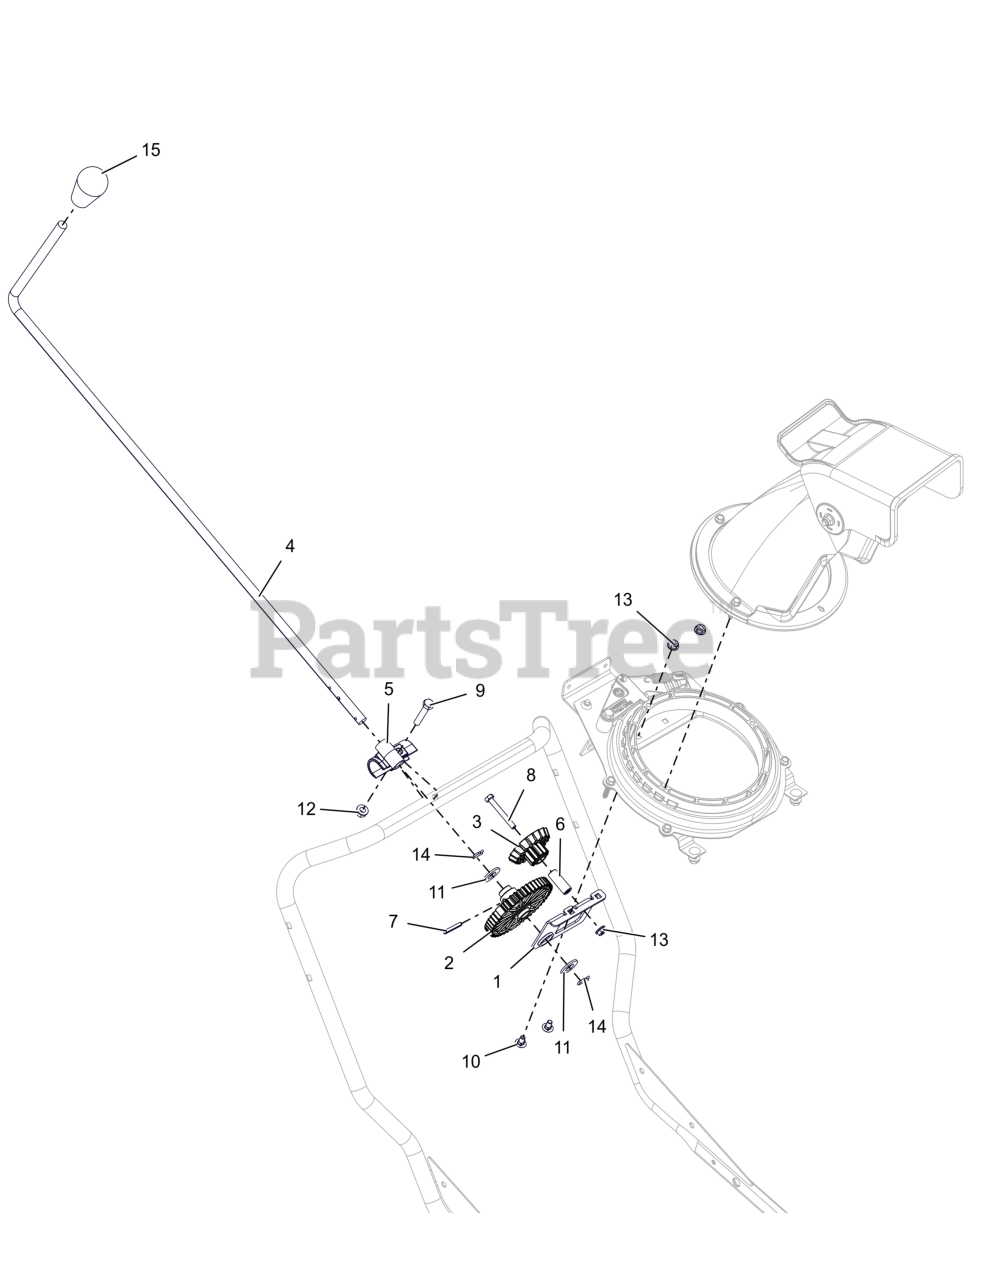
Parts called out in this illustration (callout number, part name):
1	BRKT, CHUTE ROTATION - FRONT
2	GEAR, ROTATION - REMOTE SPUR
3	GEAR, ROTATION - REMOTE COMBO
4	ROD, ROTATION - CHUTE
5	ROD, ROTATION - HOLDER
6	BSHG,SLV - .265 X .505 X 1.341
7	PIN-ROLL .188X1.25
8	BLT, HEX .25-20X2.00 G5 ZCC
9	BLT, HEX .31-18X1.75 G5 ZCC
10	BLT, RHSN .25-20X.500 G5 ZCC
11	WSHR,FLT .531X1.062X.095 ZCC
12	NUT,LK-CTR-FLG .31-18 GF ZCC
13	NUT-LK-TOP-FLG .250-20 GF ZCC
14	CLIP, SPRING
15	KNOB,SOFT-TEARDROP,PUSH-ON BLK
